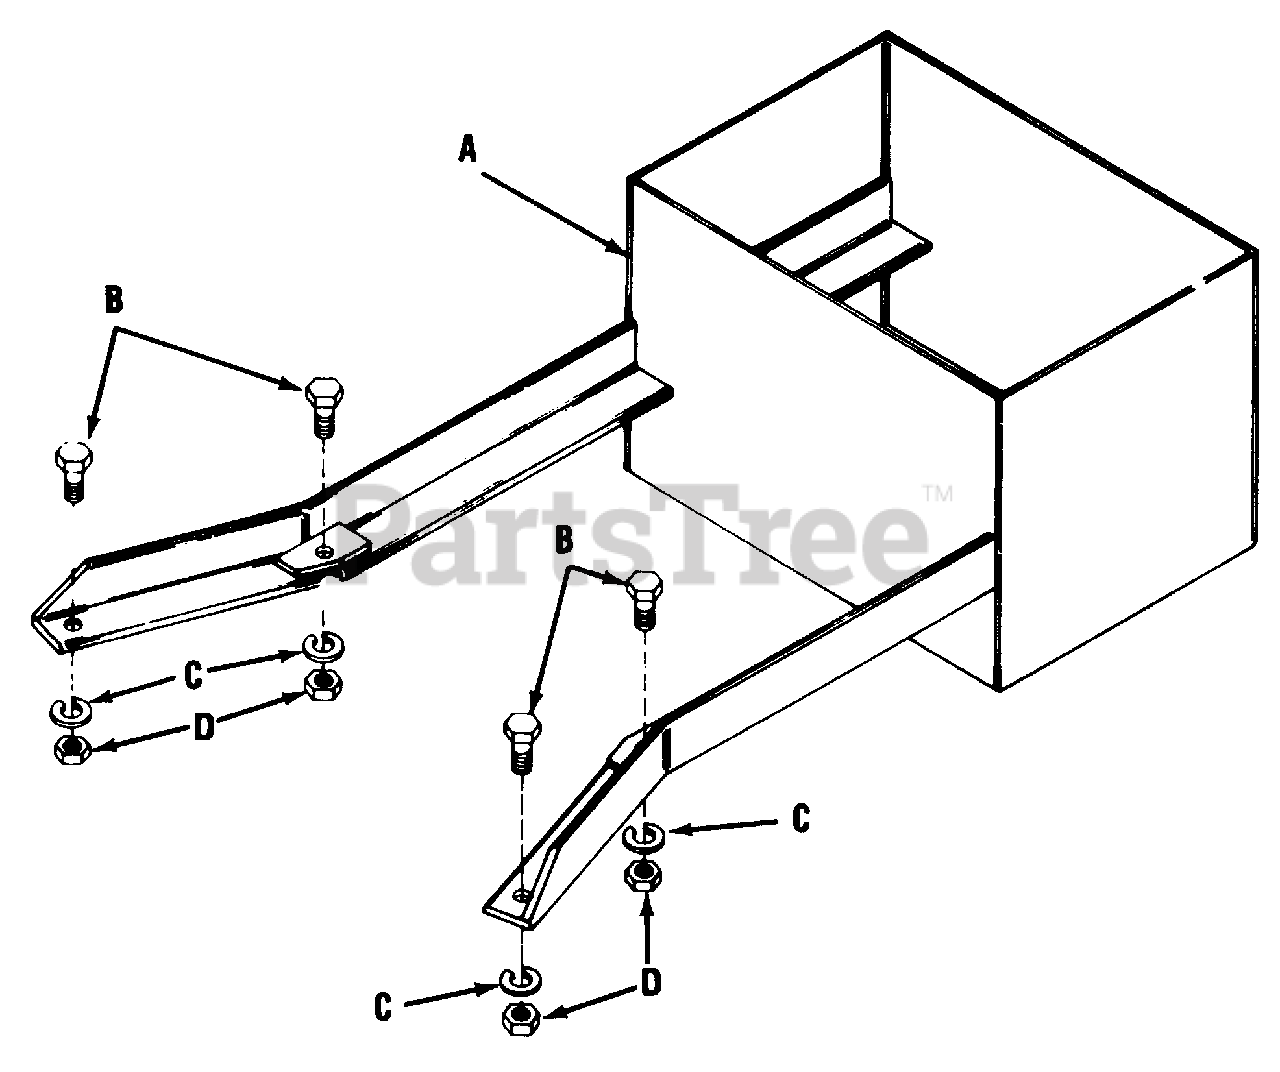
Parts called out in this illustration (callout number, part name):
A	Weight Box
B	Hex Capscrew, 1/2"-13 N.C. x 1-1/4"
C	Lock Washer, 1/2"
D	Full Hex. Nut, 1/2"-13 N.C.
